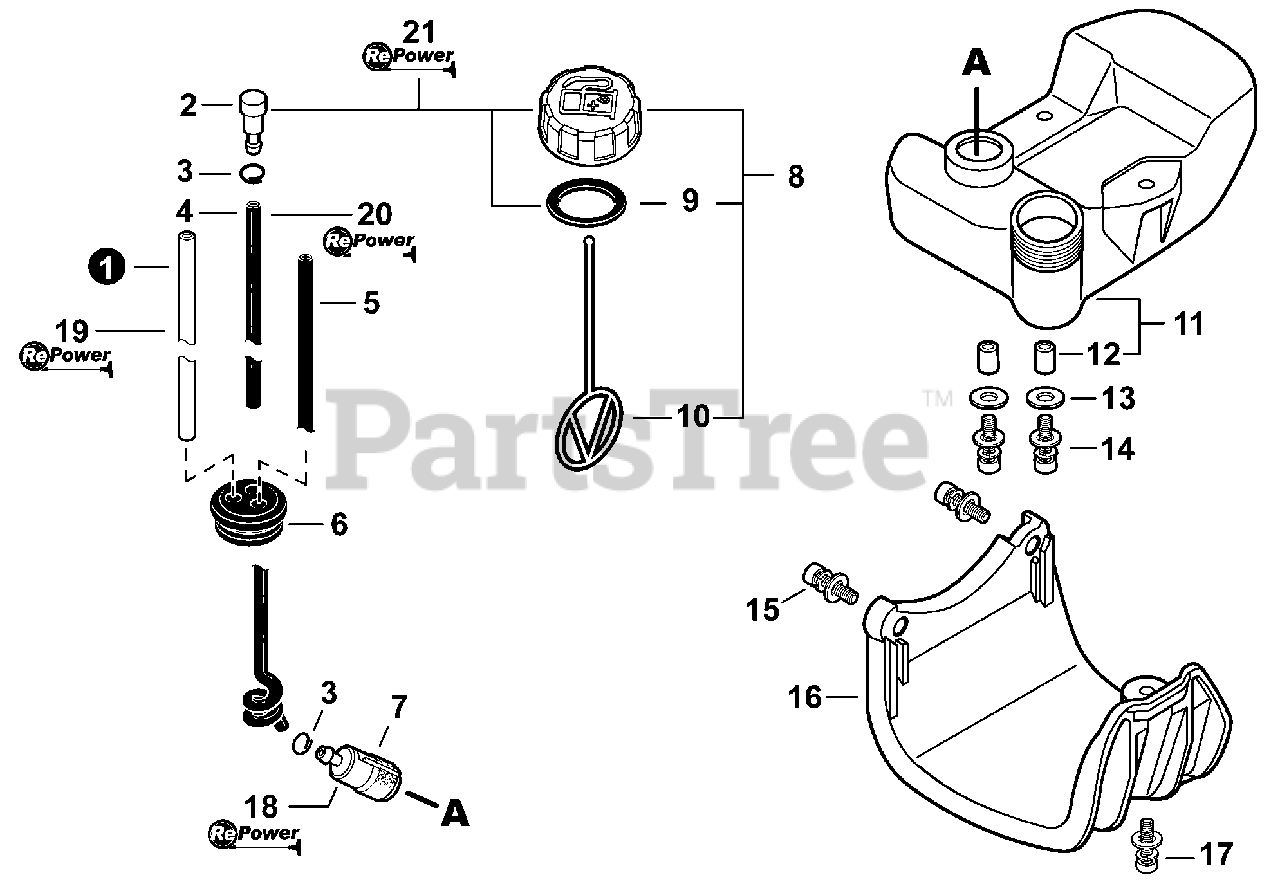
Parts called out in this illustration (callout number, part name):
1	PIPE, FUEL 3×6×80 CLEAR
2	VENT ASSY
3	CLIP 6.5MM
4	PIPE, FUEL 3×6×115 BLACK
5	PIPE, FUEL 3×6×165
6	GROMMET, FUEL
7	FILTER, FUEL
8	CAP ASSY, FUEL
9	GASKET, FUEL CAP
10	CONNECTOR, CAP L= 100mm
11	TANK, FUEL
12	SPACER 6.2×7.8×6
13	WASHER 5.5×12×0.8
14	BOLT 5×16
15	BOLT 5×22
16	GUARD, FUEL TANK
17	SCREW 5×20
18	TUNE-UP KIT - REPOWER
19	PIPE, BULK - 3×6mm CLEAR
20	PIPE, BULK - 3×6mm BLACK
21	CAP/VENT KIT - REPOWER
